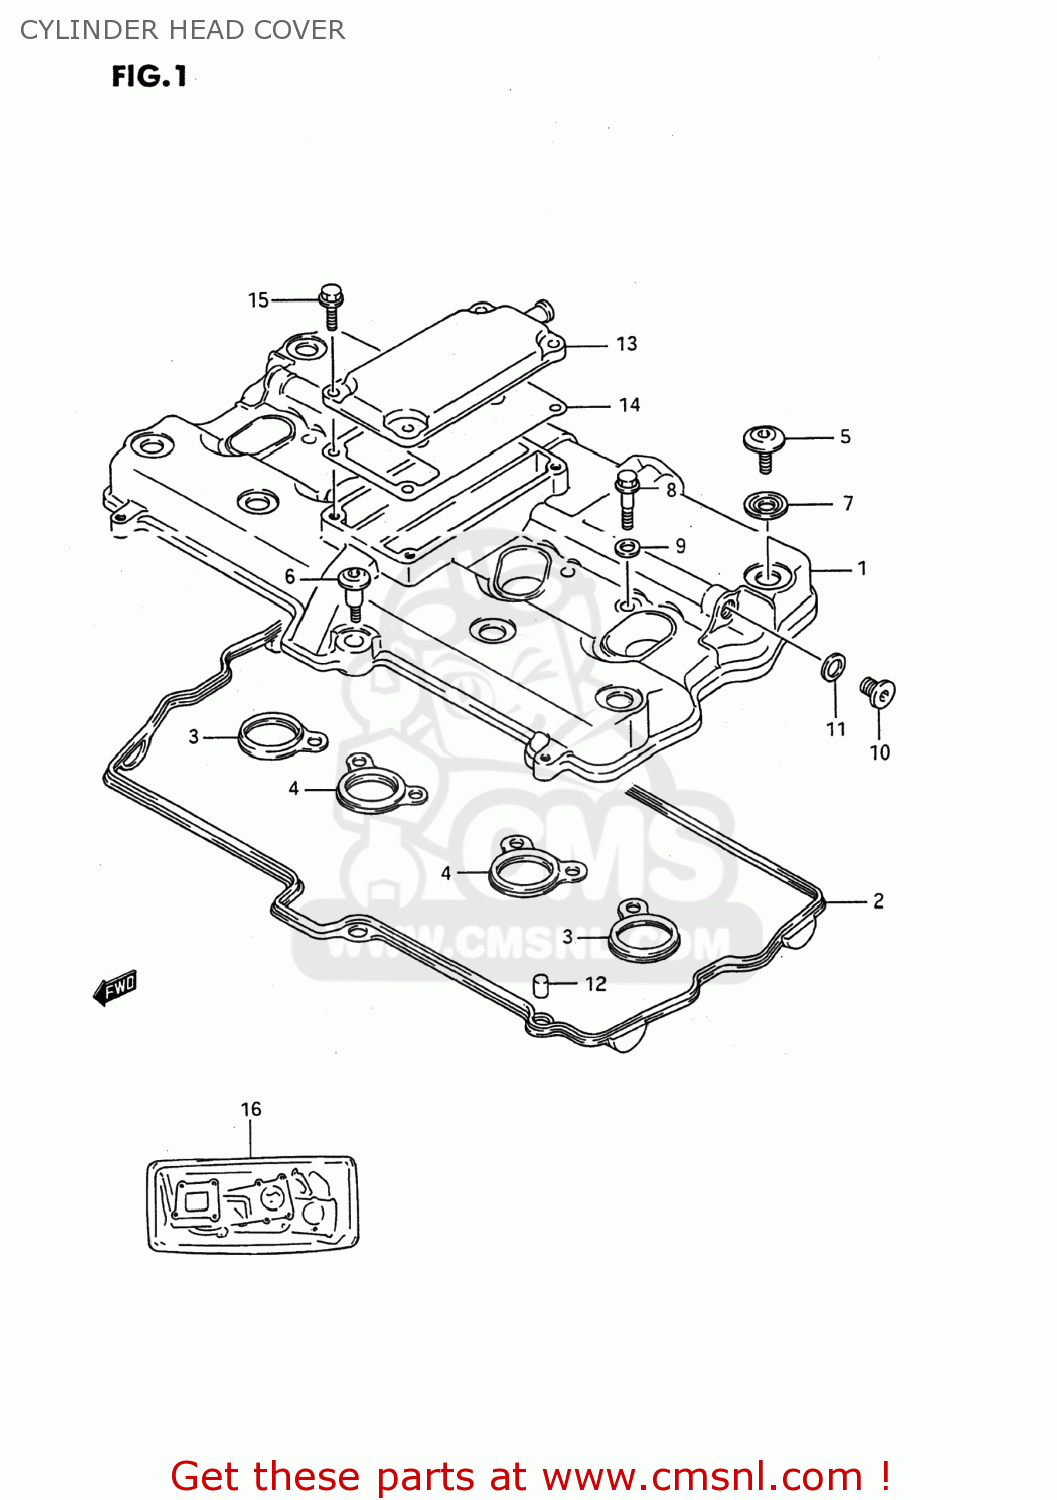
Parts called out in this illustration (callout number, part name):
1	COVER,CYLINDER HEAD
2	GASKET,CYLINDER HEAD COVER (NAS)
3	GASKET,HEAD COVER NO.2 (NAS)
4	GASKET,HEAD COVER NO.3 (NAS)
5	BOLT(7X17.5)
6	BOLT(7X31)
7	WASHER(10.6X25.5X2.3)
8	BOLT,UNION 8X35
9	GASKET 8.2X14X1 (NAS)
10	PLUG(L:12)
11	GASKET(12.1X16.2X3.7) (NAS)
12	PIN
13	COVER,BREATHER
14	GASKET (NAS)
15	BOLT 6X20
16	GASKET SET (NAS)
